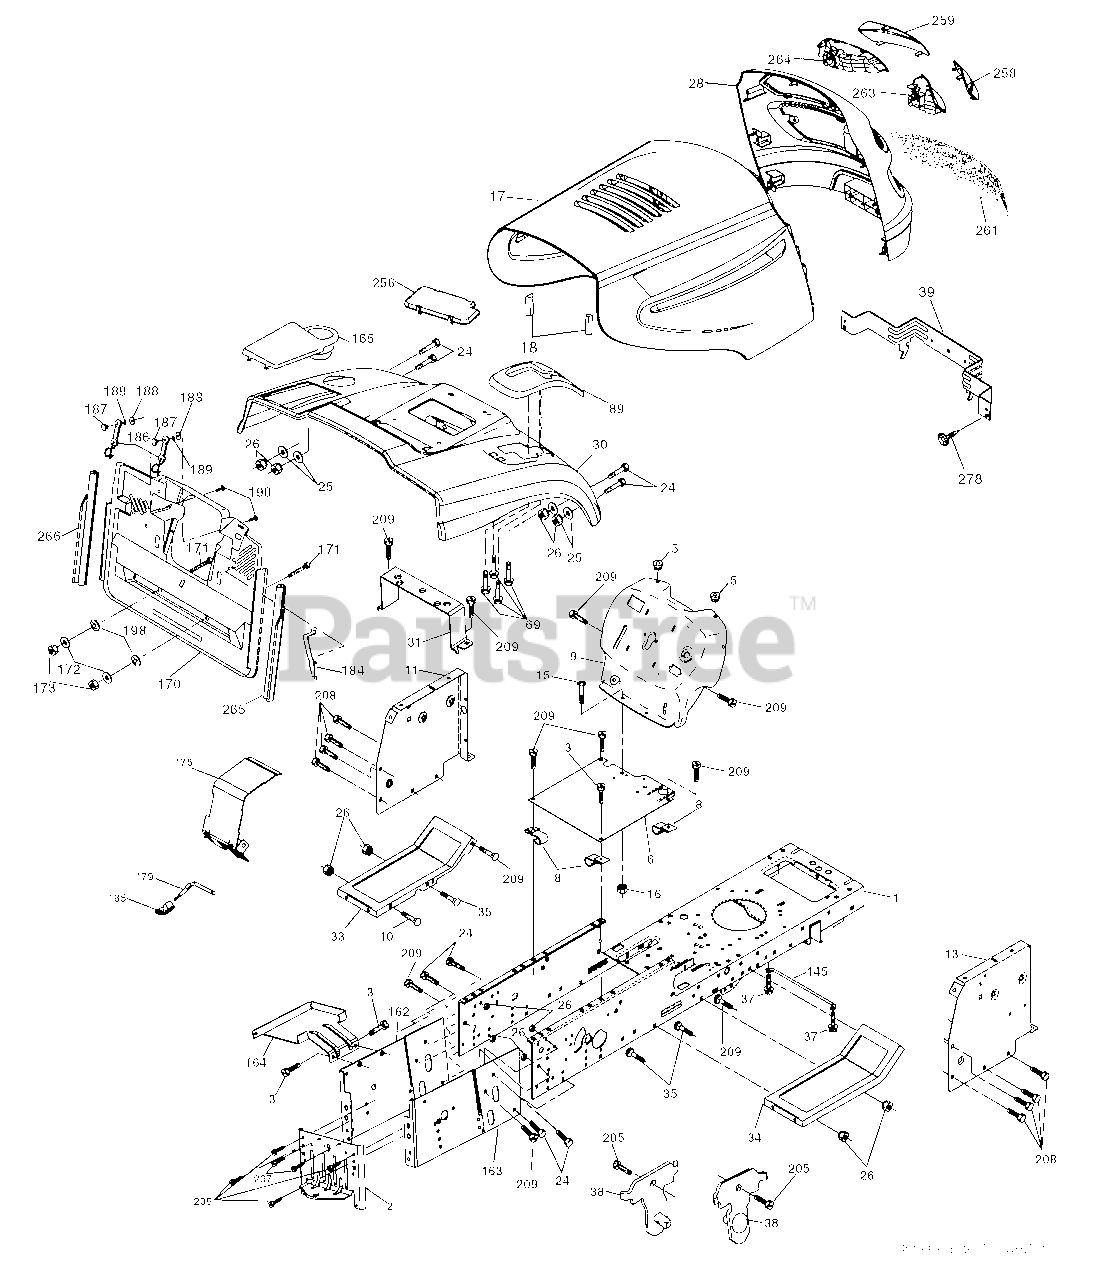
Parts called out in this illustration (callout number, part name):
1	Chassis
2	Drawbar
3	Screw 3/8-16 x 3/4
5	Bumper Hood/Dash
6	Saddle
8	Clip Insulator 13/32 Mtg. Hole
10	Bolt, Carriage 3/8-16 x 3/4
11	Panel, Dash, L.H.
13	Panel, Asm. Dash R.H.
15	Screw, Machine, Truss Head 5/16-18 unc x 3/4
16	Nut
24	Bolt
25	Washer 13/32 x 13/16 x 12 Ga.
26	Nut
28	Grille /Lens Asm
31	Bracket, Fender Support
33	Footrest, L.H.
34	Footrest, R.H.
35	Bolt
37	Screw Thdrol 5/16-18 x 1/2 TYT
38	Bracket Asm Pivot Mower Rear
39	Bracket Pivot Laser LT
69	Screw Hx Wsh Hi-Lo 1/4-1/2
89	Console Crd Auto
145	Rod Pivot Chassis/Hood
162	Bracket Exten Chassis Lh CRD
163	Bracket Exten Chassis Rh CRD
164	Support Battery CRD
165	Cover Battery
170	Backplate CRD
171	Bolt Rdhd Sqnk 3/8-16 x 2-1/2 Gr. 5
172	Washer 13/32 x 1-1/4 x 16 Ga.
173	Nut, Keps Hex 3/8-16 unc
175	Door Trap
179	Rod Pivot FBI CRD
184	Bracket Actuator Bagger CRD
185	Knob Rod Brake Parking
186	Latch Asm Mulch/Bagger
187	Nut Weld
189	Washer Lock #10
190	Screw Pan Hd Phillip 10-24 x 5/8
205	Screw Thdrol 3/8-16 x 1/2
207	Screw Thdrol 5/16-18 x 1/2
208	Screw Thdrol 3/8-16 x 1/2
209	Screw Hex Wsh Thdrol 3/8-16
256	Cover Fender Rack
258	Lens Grille RH
259	Lens Grille LH
261	Insert Grille
263	Bezel Grille RH
264	Bezel Grille LH
265	Seal Side RH Bagger
266	Seal Side LH Bagger
278	Screw 10 x 3/4 Single Head Hex
278	Plug Switch Light
